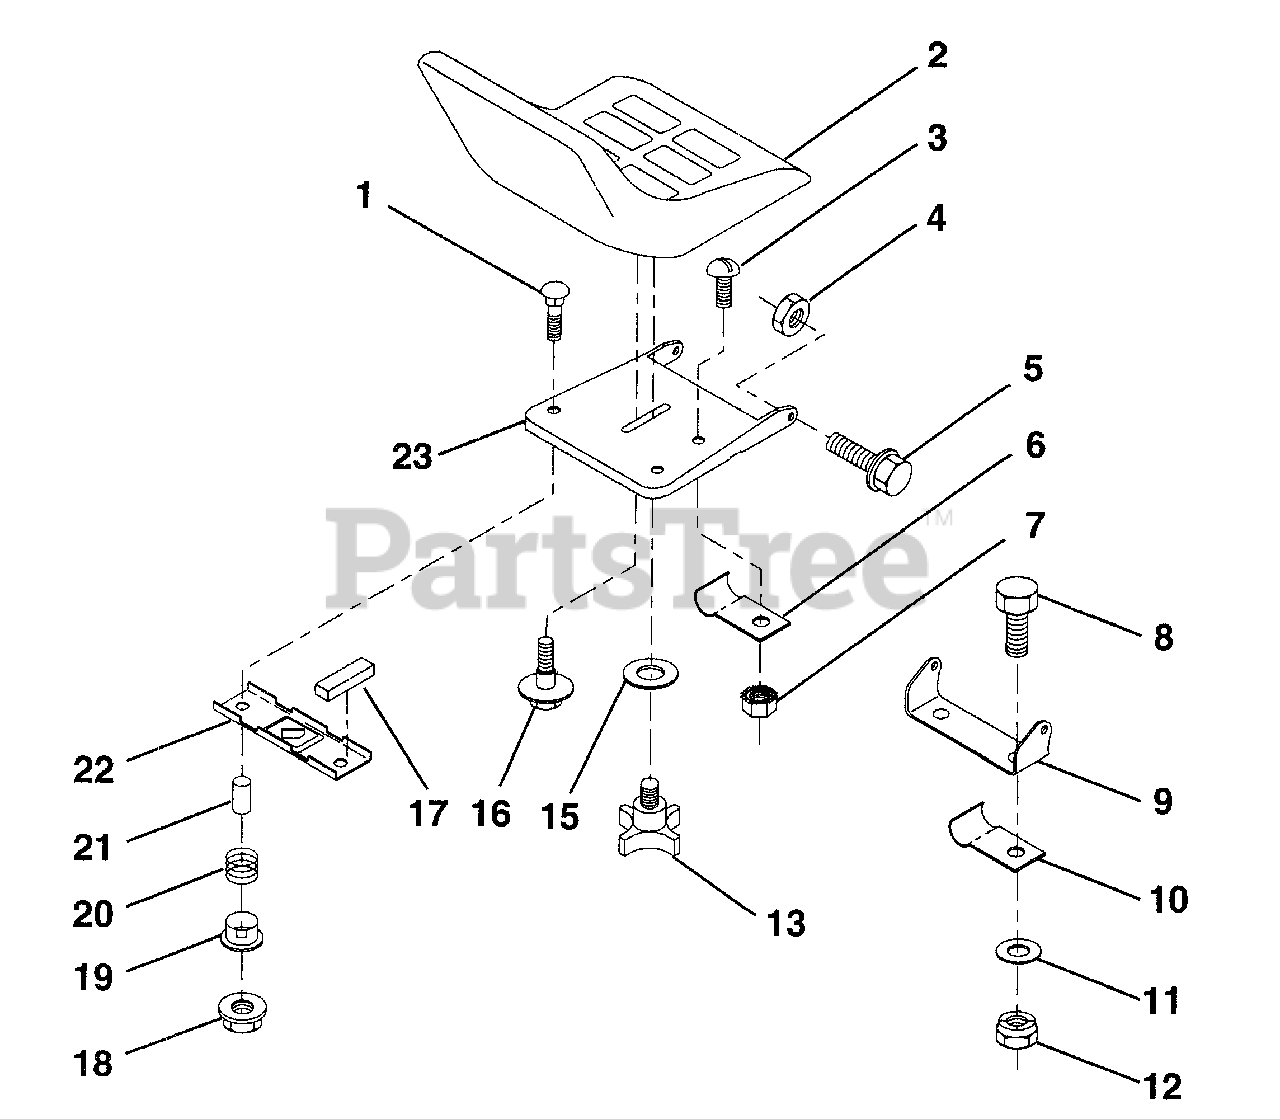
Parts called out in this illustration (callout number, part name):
1	Bolt, Carriage 1/4-20 x 1-3/8
2	Seat
3	Screw, Slotted Pan Head # 10-32 x 1/2
4	Nut, Hex, Crownlock 5/16-18
5	Bolt, Hex, Shoulder 5/16-18 UNC
6	Clip, Insulated
7	Nut, Hex, Keps #10-32 UNF
8	Bolt, Hex, Fin. 3/8-16 UNC x 3/4
9	Bracket, Pivot, Seat
10	Clip, Insulated
11	Washer 12/32 x 2 x 10 Gauge
12	Nut, Hex, Crownlock 3/8-16 UNC
13	Knob, Seat
15	Washer 17/32 x 1-3/16 x 12 Gauge
16	Bolt, Shoulder
17	Strip, Foam
18	Nut, Hex, Large, Flange Lock
19	Bushing, Snap
20	Spring, Compression
21	Spacer, Split 28 Id. x .96 Lg.
22	Bracket, Switch Mounting
23	Pan, Seat
